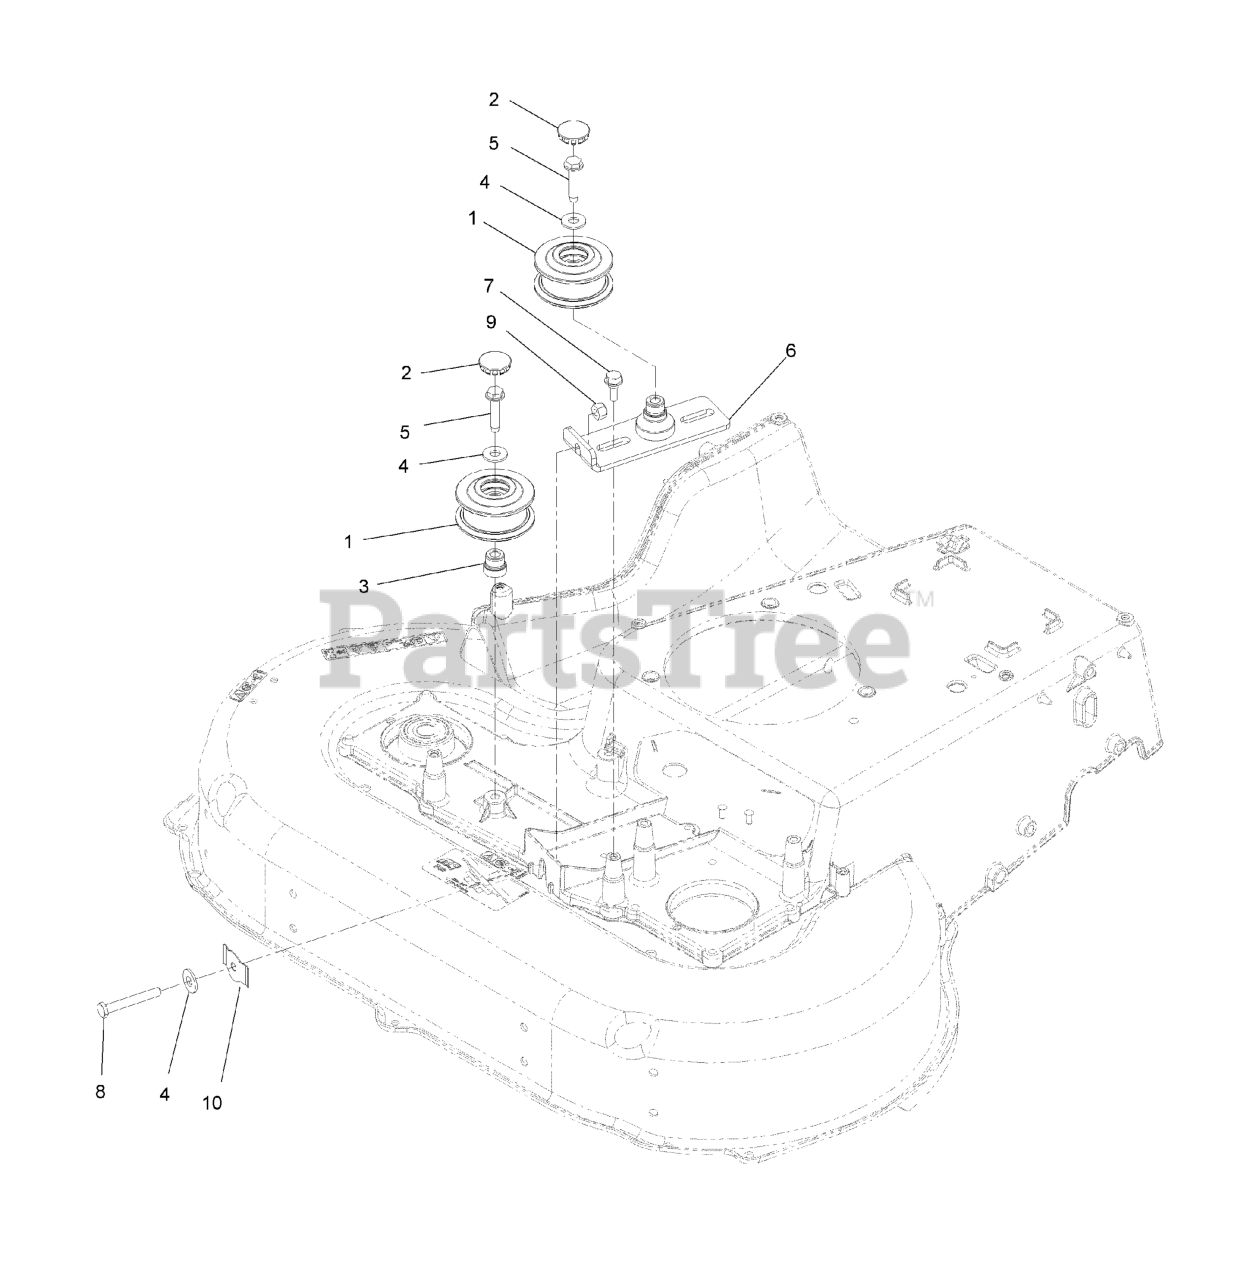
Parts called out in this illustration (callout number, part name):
1	PULLEY-IDLER, FLAT
2	PLUG-BUTTON
3	ADAPTER-BORE
4	WASHER-FLAT
6	BRACKET-IDLER
7	SCREW-SHOULDER,HWH
8	BOLT-TAP, HH
9	NUT-LOCK, NI
10	SPRING-FLAT
